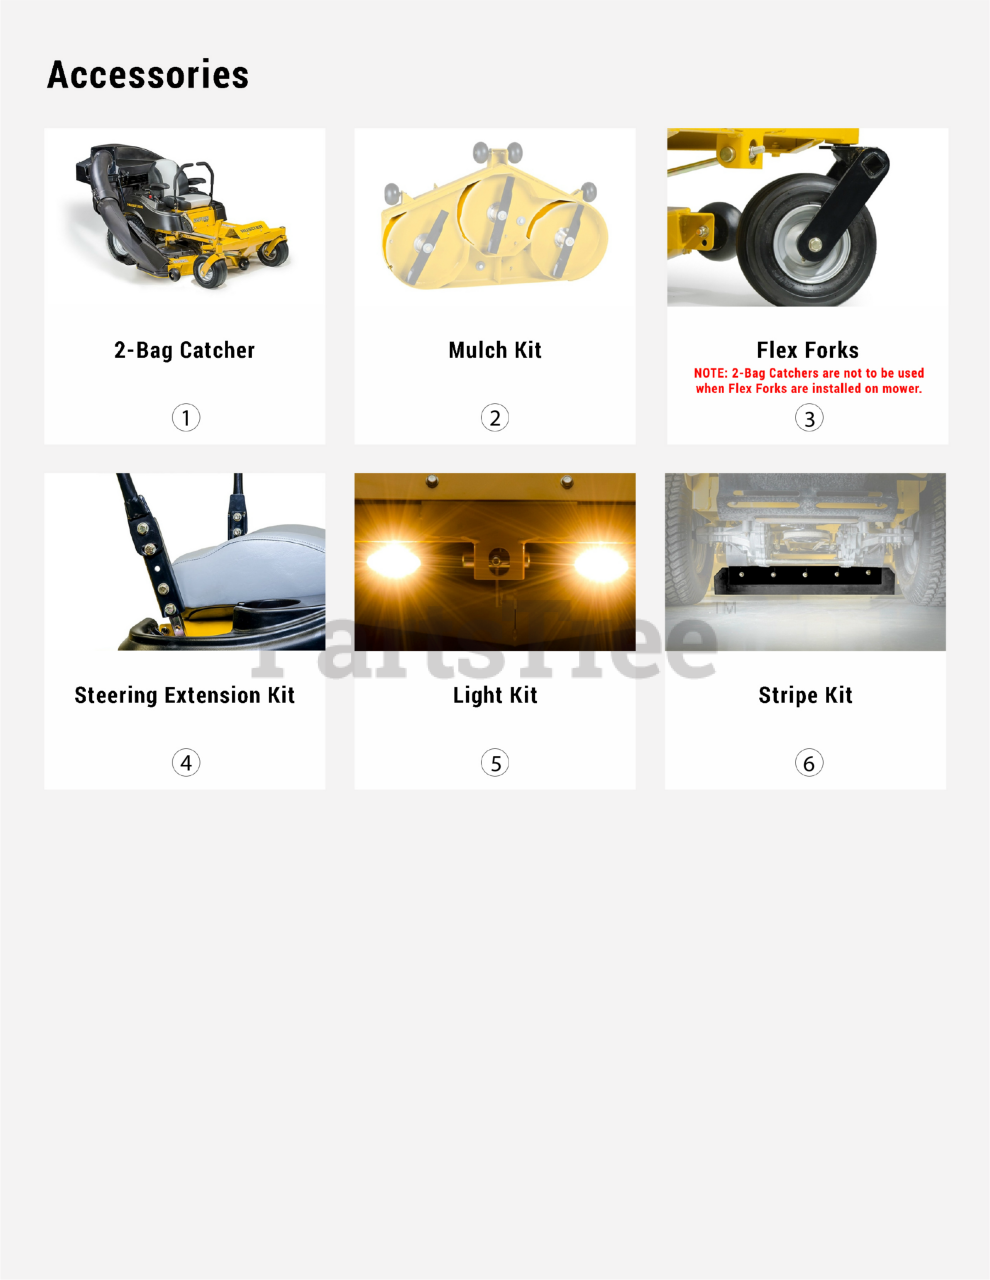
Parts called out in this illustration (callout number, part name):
1	XLRSD CATCHER
2	54" MULCH KIT
3	FLEX FORK KIT
4	STEERING ARM EXT KIT
5	KIT, LIGHTS
6	STRIPE KIT
